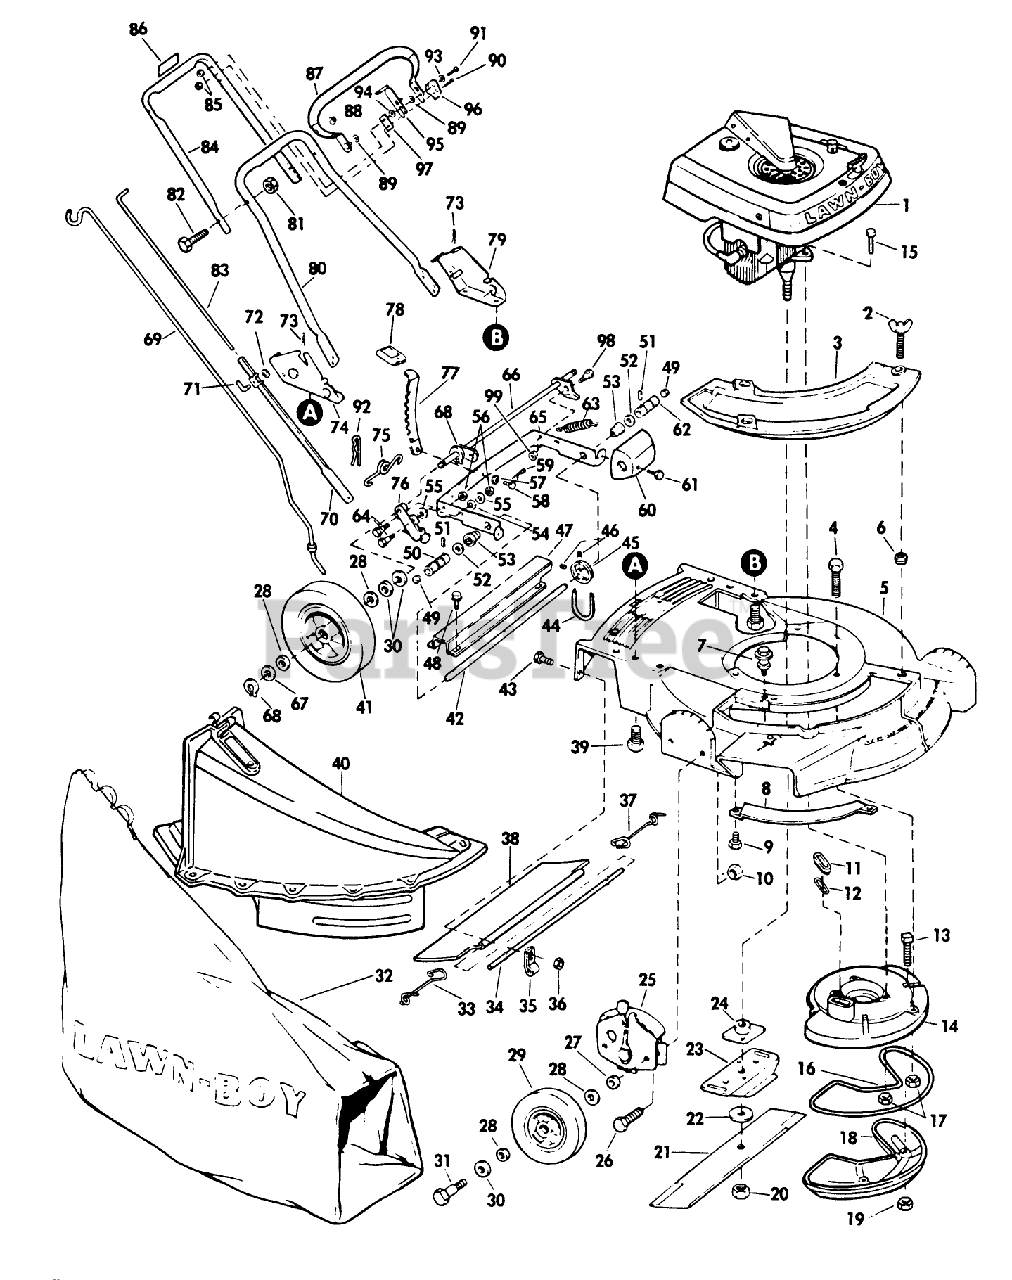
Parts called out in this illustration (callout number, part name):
1	See Note #2 at bottom of this page.
2	WING SCREW LAWRE
4	SCREW
8	BAR-TOE
10	NUT-LOCK F
11	SLEEVE
12	GASKET S
13	SCREW
17	NUT-LOCK F
20	NUT-BLADE
22	WASHER
24	PLATE AND COLLAR ASM
27	WASHER WROUGHT
28	WASHER
29	WHEEL & TIRE KIT
30	SPACER
31	BOLT WHEEL
32	89802 LB WHOLE GOODS
33	SPRING;TRAILING SHIELD RH
34	ROD 21" ADVANCE
35	CLAMP ROD KMC
36	LOCKNUT E
37	SPRIG T/SHLD ASOC
39	SCREW
42	DRIVE SHFT TAG AY
44	V-BELT
48	SCREW S
49	GREASE PLUG
51	PIN
55	WASHER S
56	STOP NUT
57	WASHER SPRING LAR
58	PIN
60	GUARD
63	SPRING
64	BOLT RB&W
67	SPACER
68	RET RING
69	ROD GRASSBAG
73	HAIR PIN
75	SPRING N.A.S
77	LEVER
78	KNOB
81	LOCKNUT E
82	SCREW
83	ROD CONTROL
85	LOCKNUT E
89	WASHER M
90	SCREW-HANDLE STOP
91	BOLT PIONEER
94	WASHER
95	LEVER LOCKOUT
97	HANDLE STOP
98	BOLT RB&W
99	LOCKNUT E
